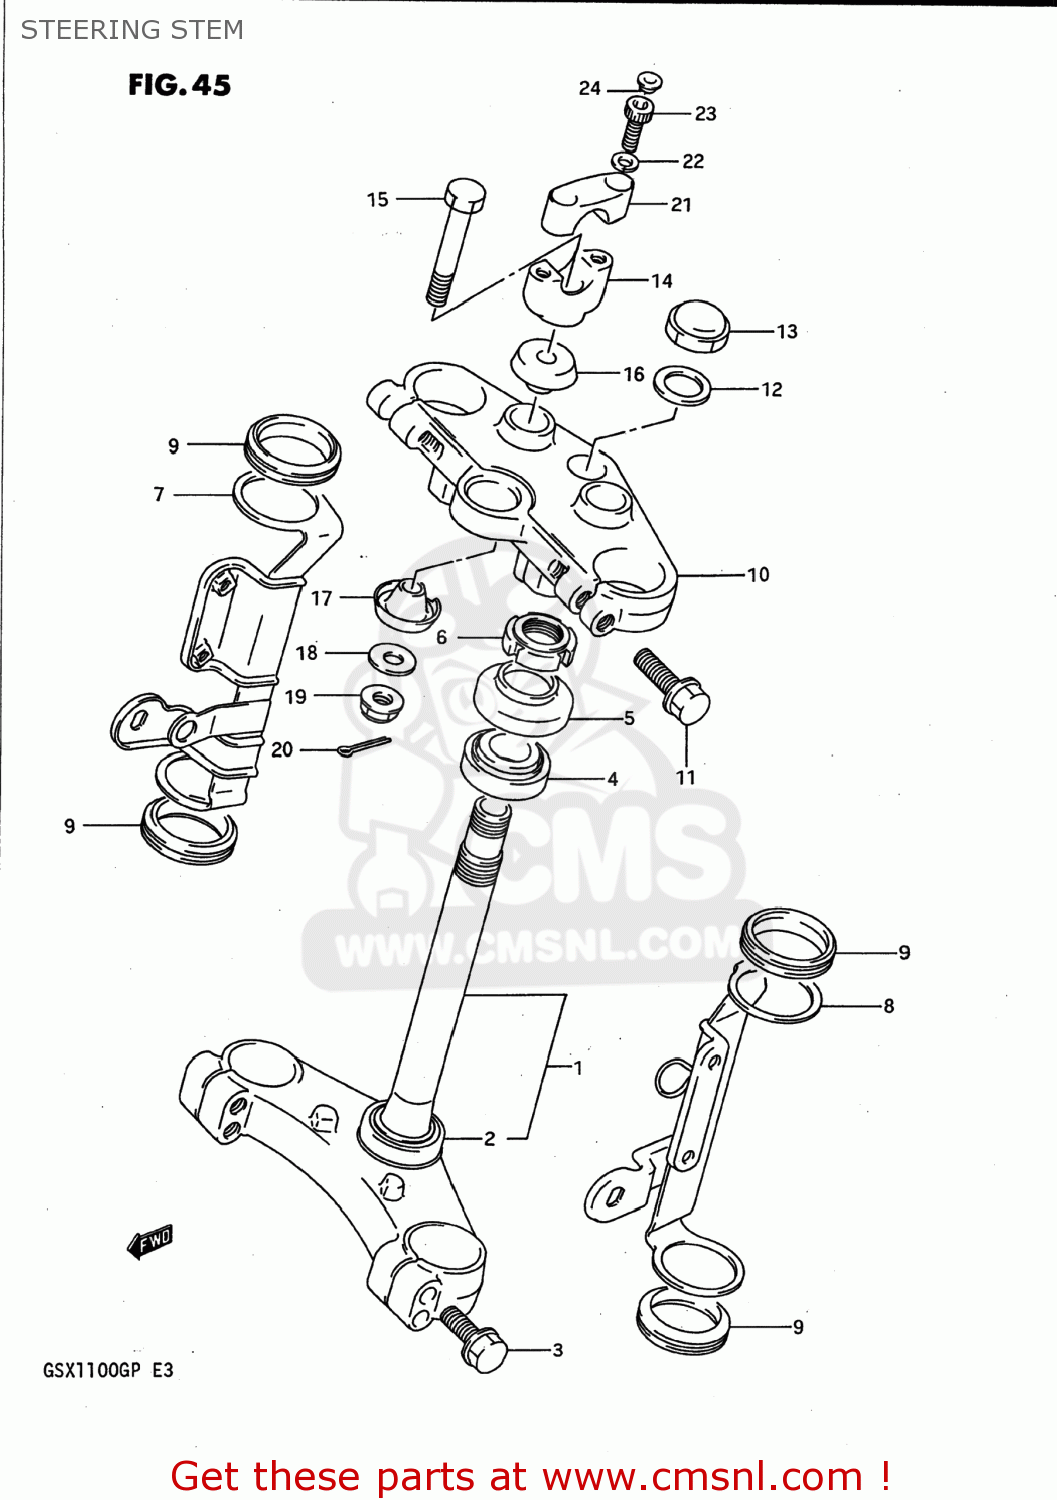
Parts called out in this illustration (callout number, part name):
1	STEM,STEERING
2	BEARING(30X55X17)
3	BOLT
4	TAPER,ROLLER BEARING
5	DUST SEAL,STEERING,UPPER
6	NUT,STEERING STEM(25X44X10)
7	BRACKET COMP,HEADLAMP
8	BRACKET,HEADLAMP,LEFT
9	CUSHION,HEADLAMP BRACKET
10	HEAD,STEERING STEM
11	BOLT 10X45
12	WASHER(22.5X32X1.6)
13	NUT,CAP
14	HOLDER,HANDLE,LOWER
15	BOLT
16	RUBBER,DAMPER,UPPER
17	DAMPER,LWR
18	WASHER,HANDLEBAR HOLDER
19	NUT
20	COTTER PIN
21	HOLDER,HANDLE,UPPER
22	WASHER
23	BOLT, LH
24	CAP(OD:14.5)
